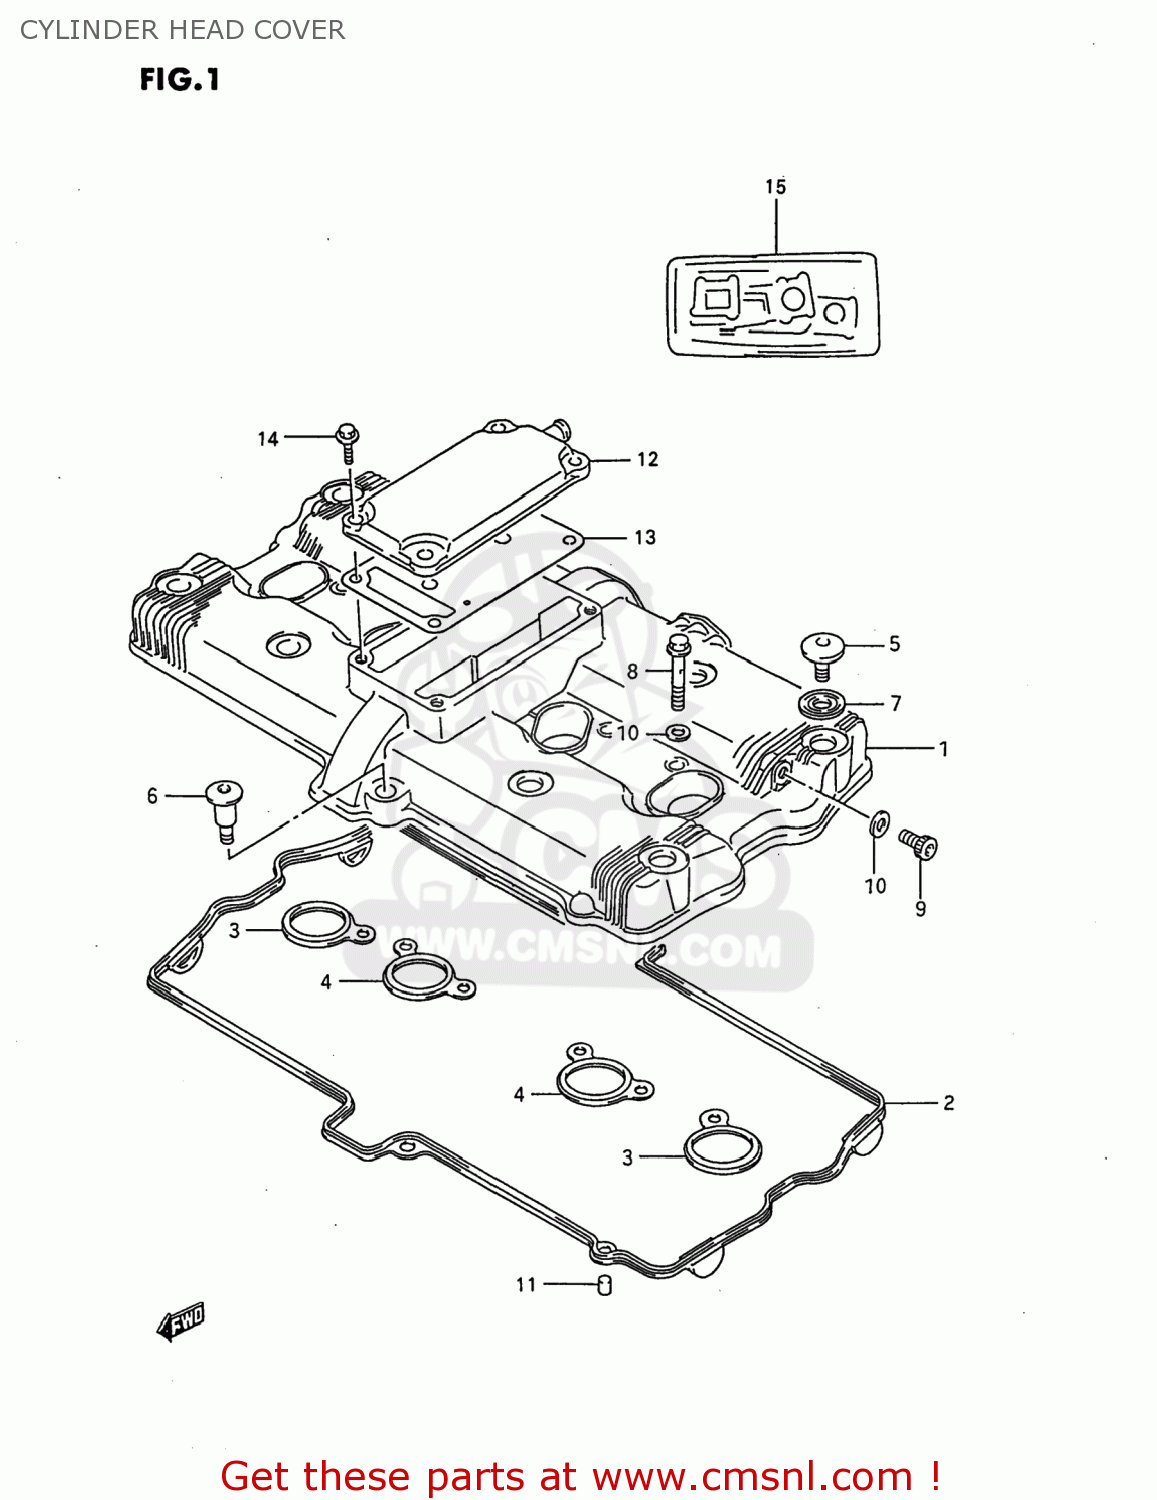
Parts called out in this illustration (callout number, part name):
1	COVER,CYLINDER HEAD
2	GASKET,CYLINDER HEAD COVER (NAS)
3	GASKET,HEAD COVER NO.2 (NAS)
4	GASKET,HEAD COVER NO.3 (NAS)
5	BOLT(7X17.5)
6	BOLT(7X31)
7	WASHER(10.6X25.5X2.3)
8	BOLT,UNION 8X35
9	PLUG
10	GASKET 8.2X14X1 (NAS)
11	PIN
12	COVER,BREATHER
13	GASKET,BREATHER (NAS)
14	BOLT
15	GASKET SET (NAS)
